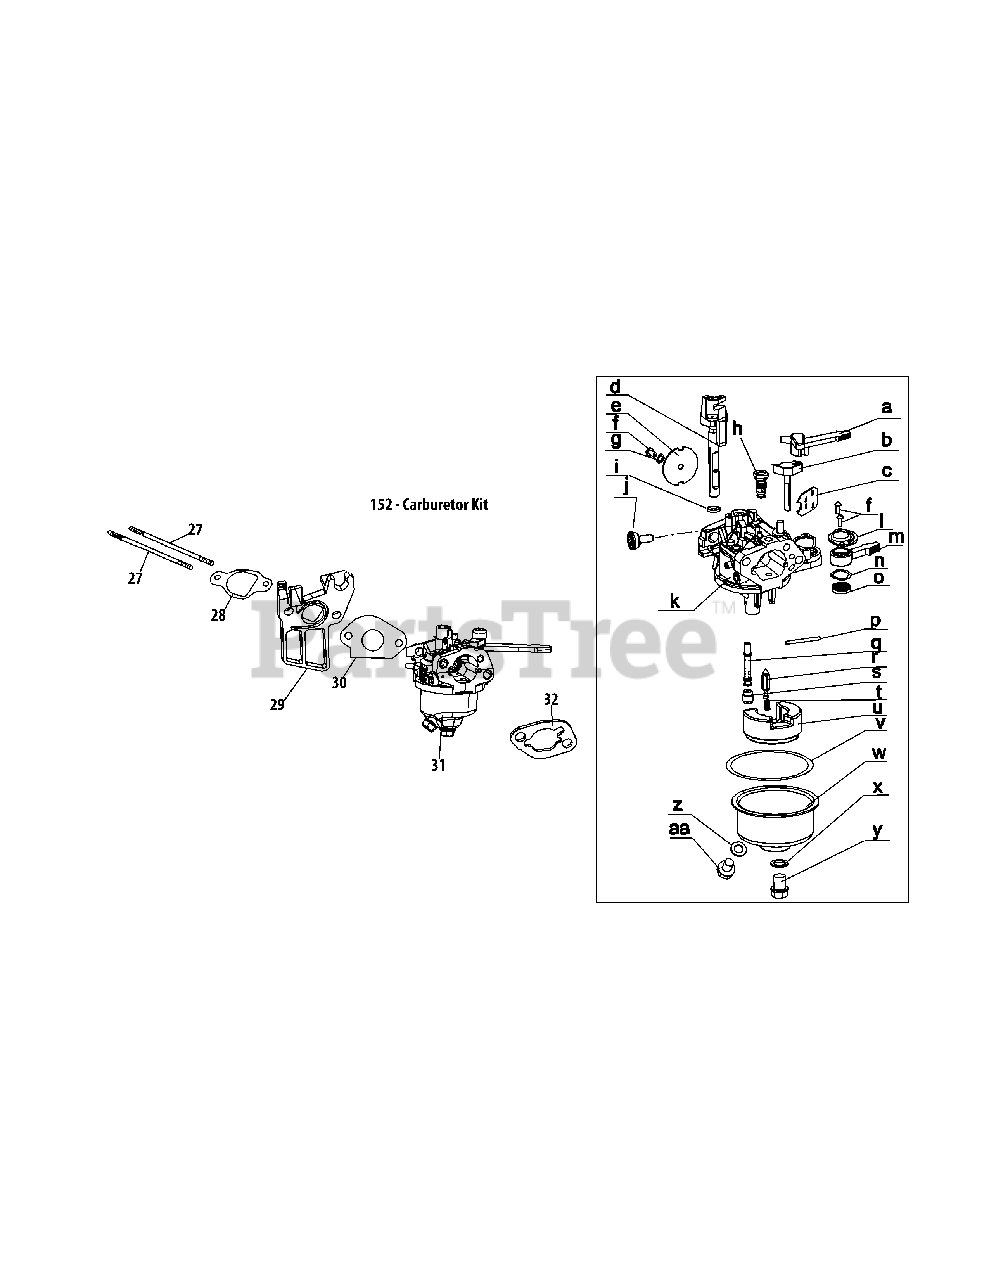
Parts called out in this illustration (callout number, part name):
27	Stud M6×110
28	Carburetor Insulator Gasket
29	Carburetor Insulator
30	Carburetor Gasket
31	Carburetor Assembly
32	Carburetor Gasket Plate
152	Carburetor Kit
